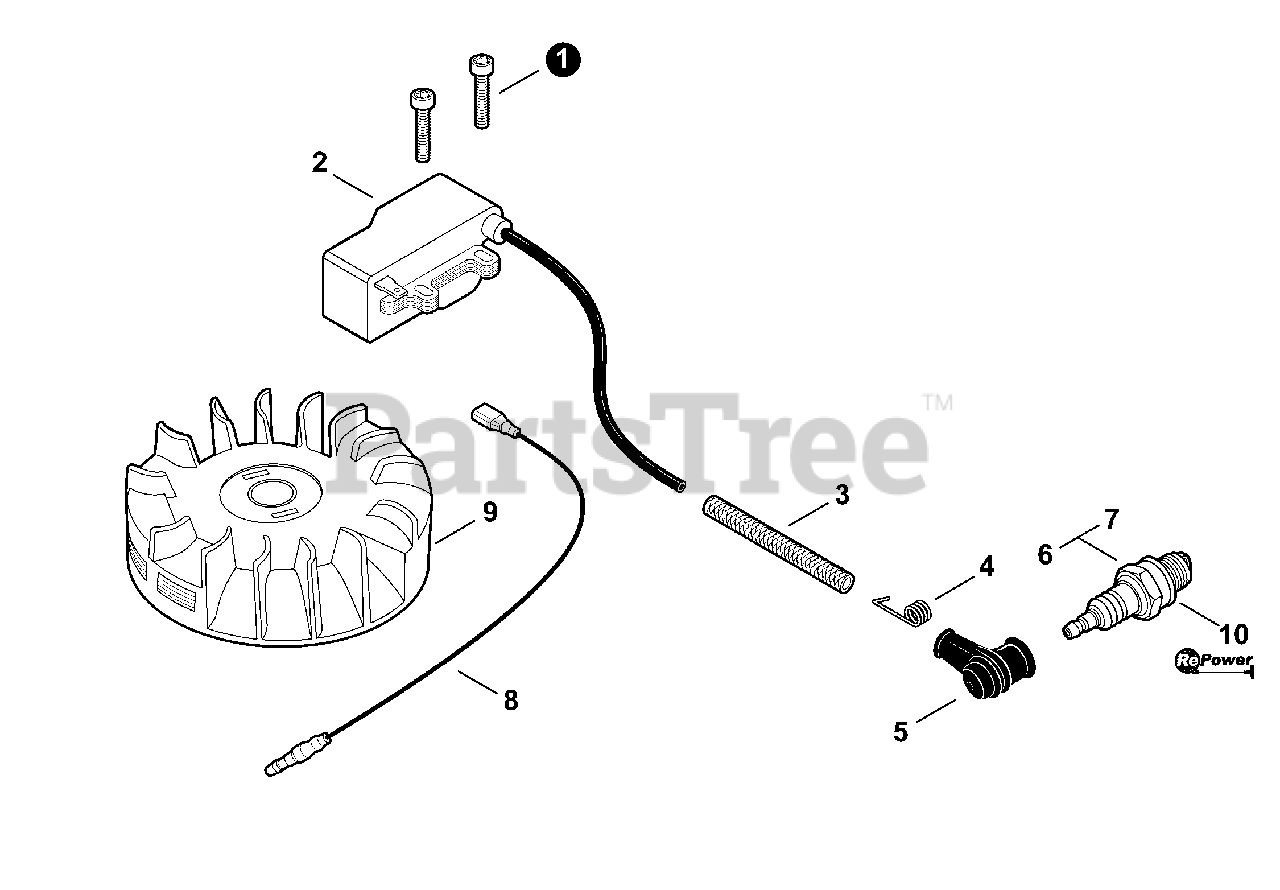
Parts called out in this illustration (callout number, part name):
1	BOLT, TORX 4×20
2	COIL, IGNITION
3	TUBE, INSULATOR
4	TERMINAL, SPARK PLUG
5	CAP, SPARK PLUG
6	SPARK PLUG - BPM8Y
7	SPARK PLUG - BPMR8Y
8	LEAD - IGNITION
9	FLYWHEEL
10	TUNE-UP KIT - REPOWER
